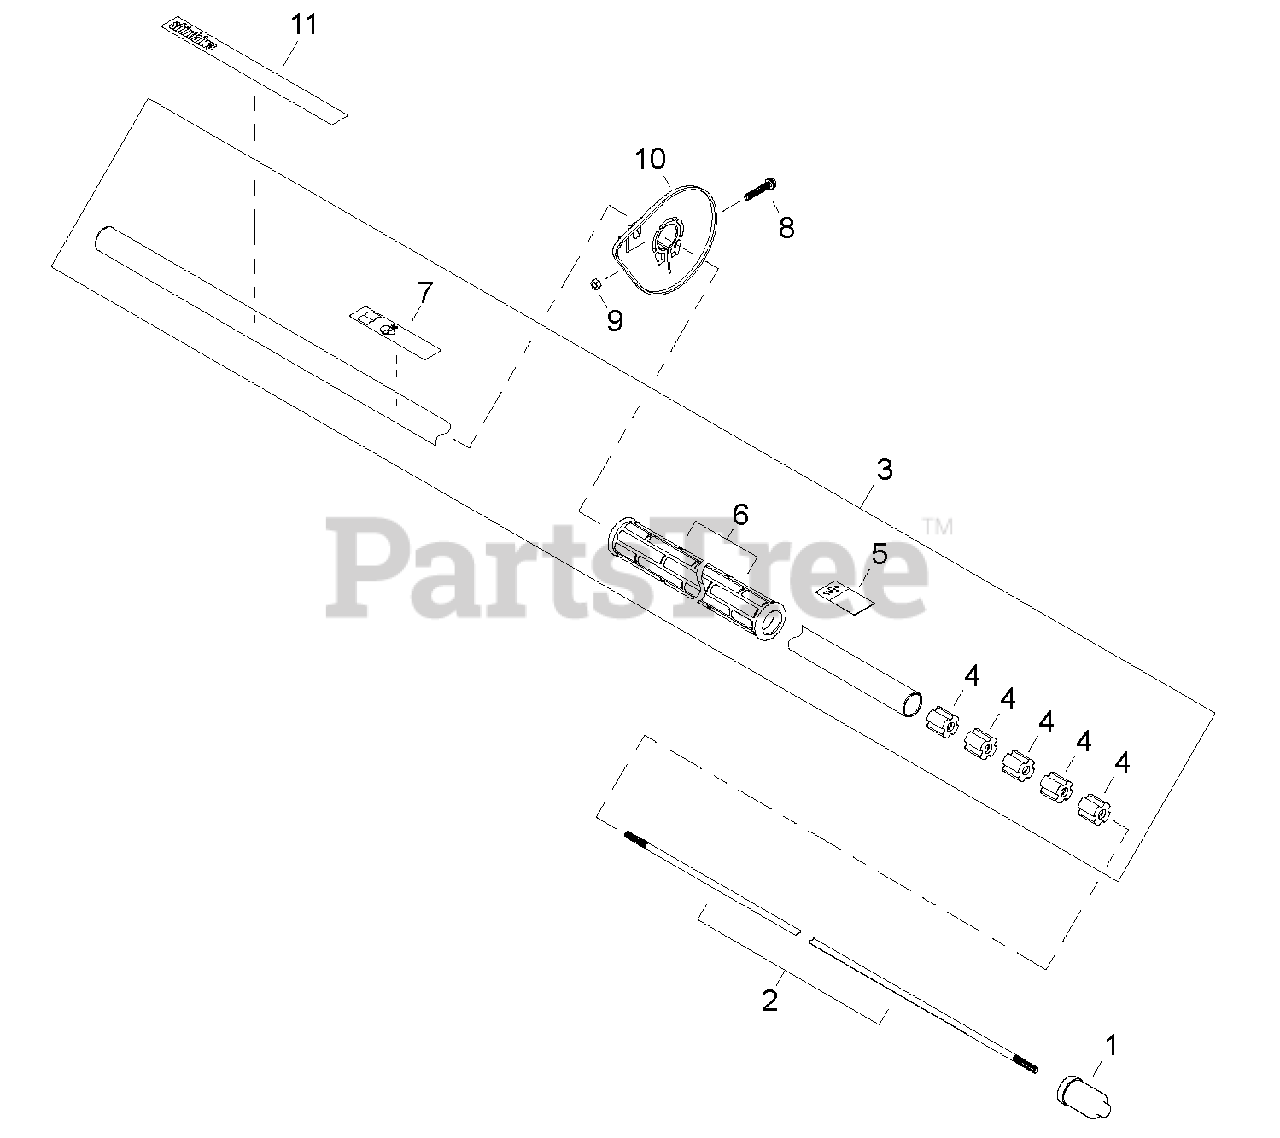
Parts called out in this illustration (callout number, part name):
1	CAP
2	MAINSHAFT
3	MAIN PIPE ASSY WITH GRIP
4	BUSHING
5	LABEL, HIGH VOLTAGE
6	GRIP, FRONT
7	LABEL, CAUTION
8	SCREW M5×30
9	NUT M5
10	GUARD, HAND
11	LABEL, SHINDAIWA PROFESSIONAL
